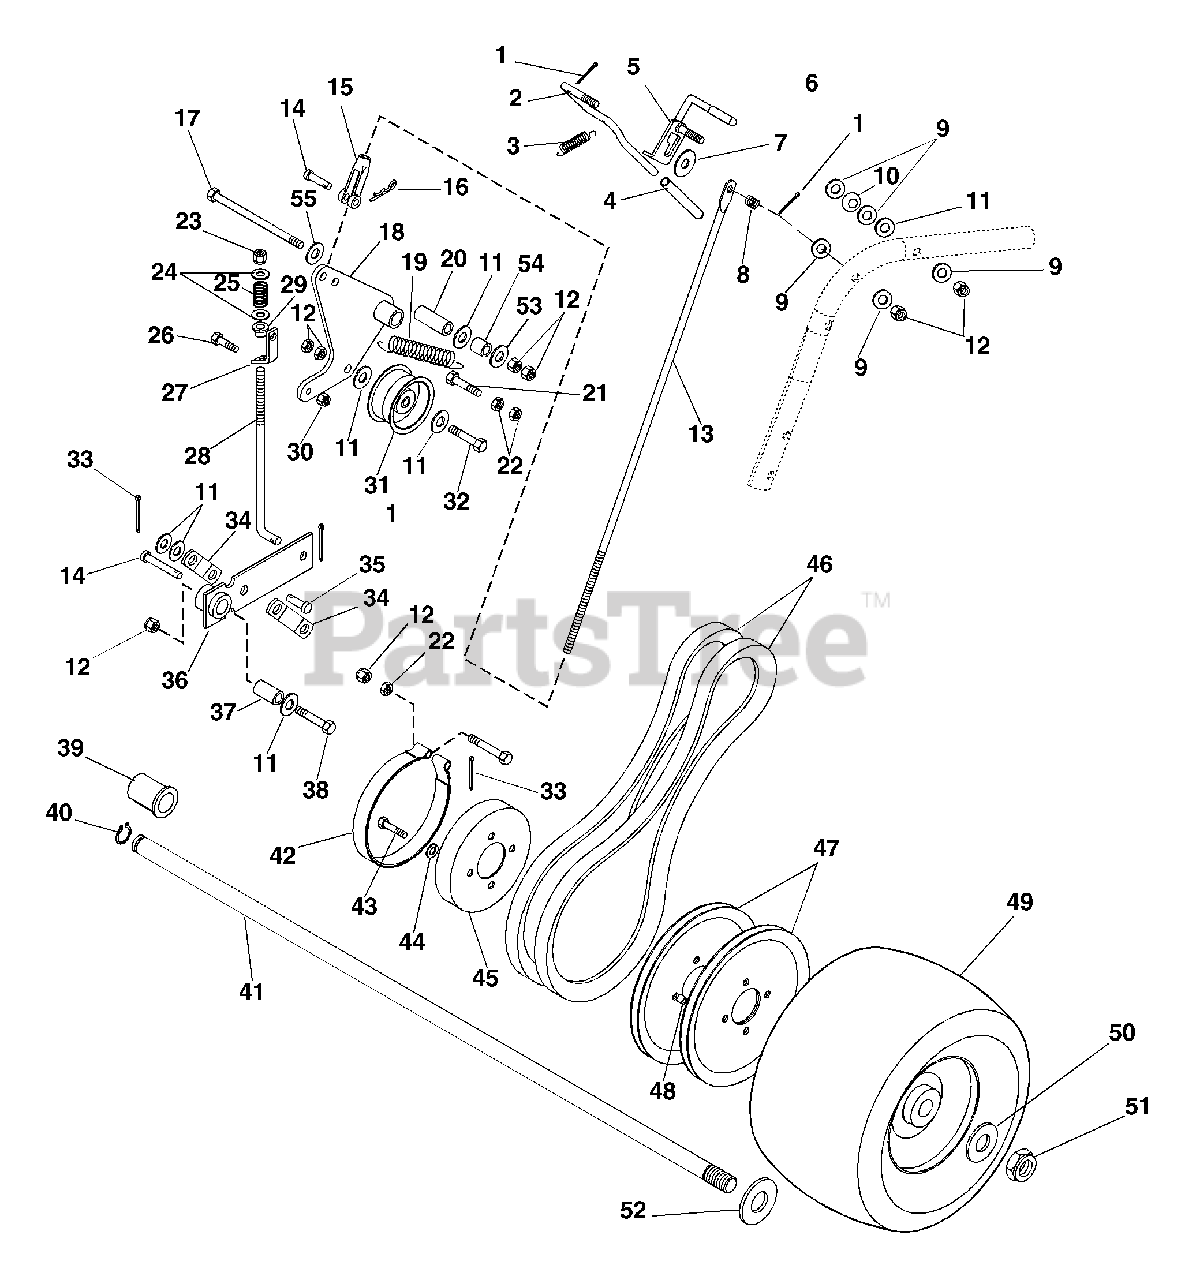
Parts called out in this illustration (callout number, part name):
1	Pin-Cotter .09 x .75
2	Lever-Hand Control
3	Spring-Tension .041 x .500 x 1.75
4	Grip-Hand Clutch Lever
5	Weldment-Clutch-Brake Lock
6	Tip-Brake Lock Lever
7	Washer-Flat-Steel .4 x 1.375
8	Spring-Compression .045 x .60 x .75
9	Washer-Flat-Nylon .375 x .75 x .060
10	Spring Washer
11	Washer-Flat-Steel .406 x .812 x .065
12	Nut-Locking-Center .38-16
13	Rod-Clutch Actuating
14	Pin-Clevis .38 x 1.25
15	Clevis .38-24 Adjustable
16	Pin-Hair Internal .08 x .18 x 1.18
17	Bolt-Hex .38-16 x 4.00 Grade 5
18	Weldment-Wheel Clutch Arm
19	Spring-Tension .069 x .62 x 3.50
20	Bushing-Sleeve .385 x .610 x 1.80
21	Bolt-Hex .38-16 x 1.50 Grade 5
22	Nut-Hex .38-16
23	Nut-Locking-Center .31-18
24	Washer-Flat-Steel .344 x .688 x .065
25	Spring-Compression .125 x .78 x 1.00
26	Bolt-Hex .25-20 x .75 Grade 5
27	Left-Bracket-Pro Brake Link
28	Rod-Brake
29	Bushing-Flange .320 x .620 x .312
30	Nut-Locking-Center .25-20
31	Sheave 3.25 x 1.25
32	Bolt-Hex .31-18 x 2.25
33	Pin-Cotter .12 x .75
34	Link-Brake Arm
35	Pin-Clevis .38 x .75
36	Weldment-Brake Arm
37	Bushing-Sleeve .391 x .622 x .950
38	Bolt-Hex .38-16 x 2.00 Grade 5
39	Bushing-Flange 1.010 x 1.38 x 1.4 x 1.65
40	Ring-Retaining-External .906 x .078
41	Axle Shaft-Pro-150
42	Assembly-Brake Band-Pro
43	Bolt-Hex .31-18 x 1.50 Grade 5
44	Washer-Lock .31 x .078
45	Drum-Brake
46	Drive Belt-Matched Pair
47	Pulley-V 9.00 x 3.75
48	Bushing-Sleeve .385 x .625 x .475
49	Assembly-Wheel, 13 x 6.00-6
50	Washer-Flat-Steel 1.010 x 1.505 x .062
51	Nut-Locking-Center .44 -14
52	Washer-Thrust 1.55 x 1.002 x .093
53	Washer-Flat-Steel .38 x .87 x .179
54	Bushing
55	Washer-Flat-Steel .44 x 1.625 x .315
